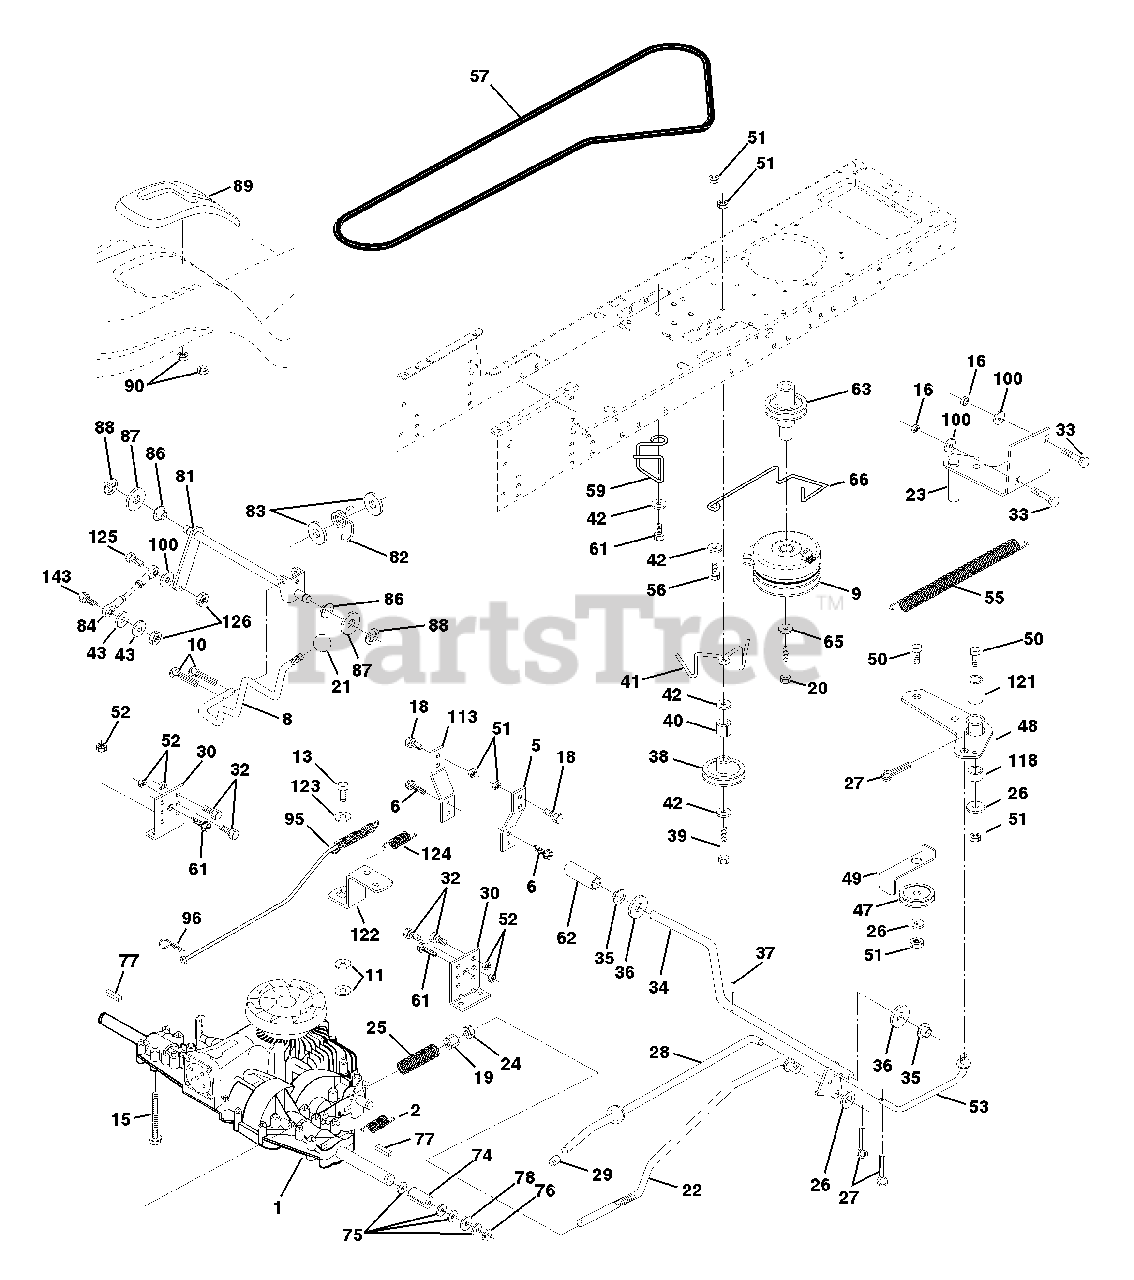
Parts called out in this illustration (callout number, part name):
1	Transaxle
2	Spring, Return Brake
5	Strap Torque
6	Screw Thdrol 5/16-18 x 3/4
8	Rod Shift Hydro LT
9	Clutch Elect
10	Pin Cotter 1/8 x 1 CAD
13	Bolt 1/4-28 Unf Gr. 8 W/Patch
15	Bolt Hex Flghd 5/16-18 Gr. 5
16	Nut Lock Hx w/Ins 5/16-18 UNC
18	Bolt Fin Hex 3/8-16 Unc x 1 Gr. 5
19	Nut Lock Hex W/Wsh 3/8-16 Unc
20	Bolt Hex 7/16-20 x 4-1/4 5 Ga. 1.38
22	Rod, Brake
23	Bracket Asm Mtg. Cl
24	Nut, Hex Jam 3/8-16 Unc
25	Spring, Brake Rod
26	Washer
27	Pin Cotter 1/8 x 3/4 CAD.
28	Rod, Parking Brake
29	Cap, Parking Brake
30	Bracket, Transaxle
32	Bolt Hex Hd 5/16-18 Unc x 3/4
33	Bolt Rd Hd Sqnk 5/16-18 Unc x 3/4
34	Shaft, Foot Pedal
35	Bearing, Nylon
37	Pin, Roll
38	Pulley, Idler, Flat
40	Spacer, Split
41	Keeper, Belt, Idler
42	Washer 13/32 x 13/16 x 12 Gauge
43	Washer 11/32 x 5/8 x 12 Ga.
47	Pulley, Idler, V-Groove
48	Bellcrank Assembly
49	Retainer, Belt
50	Bolt
51	Nut Crownlock 3/8-16 UNC
52	Nut, Crownlock 5/16-18 Unc
53	Link, Clutch
55	Spring, Return, Clutch
56	Bolt Hex 3/8-16 x 1-1/4
57	V-Belt, Ground Drive
59	Keeper, Center Span
61	Screw Thdrol. 3/8-16 x 3/4 Ty. TT
62	Cover, Pedal
63	Pulley, Engine
65	Washer
66	Keeper Belt Engine
74	Spacer, Axle PVST
75	Washer 25/32 x 1-1/4 x 16 Gauge
77	Key, Square
78	Washer 25/32 x 1-5/8 x 16 Gauge
81	Shaft Asm. Cross Hydro
82	Spring Torsion T/A
83	Washer 17/32 x 3/4 x 16 Ga.
84	Rod, Tie PVST 18"
86	Bushing Rod Strig. 629/632 ID
87	Washer 21/32 x 1-1/4 x 16 Ga.
88	Ring Klip #5304-62
89	Console, Shift
90	Nut Self-Thd Wsh-Hd 1/4 Zinc
95	Rod Asm Bypass PVST
96	Retainer Spring 1" Zinc/Cad
100	Washer 11/32 x 3/4 x 16 Ga.
113	Strap Torque LH LT
118	Spacer Bellcrank
121	Nyliner Clutching STL
122	Plate Bypass PVST
123	Washer 9/32 x 5/8 x 16 Ga.
124	Spring Return PVST
125	Bolt Fin Hex 5/16-18 Unc x 1
126	Nut Lock 5/16-18 Unc
143	Bolt Fin Hex 5/16-18 UNC x 1-1/4
